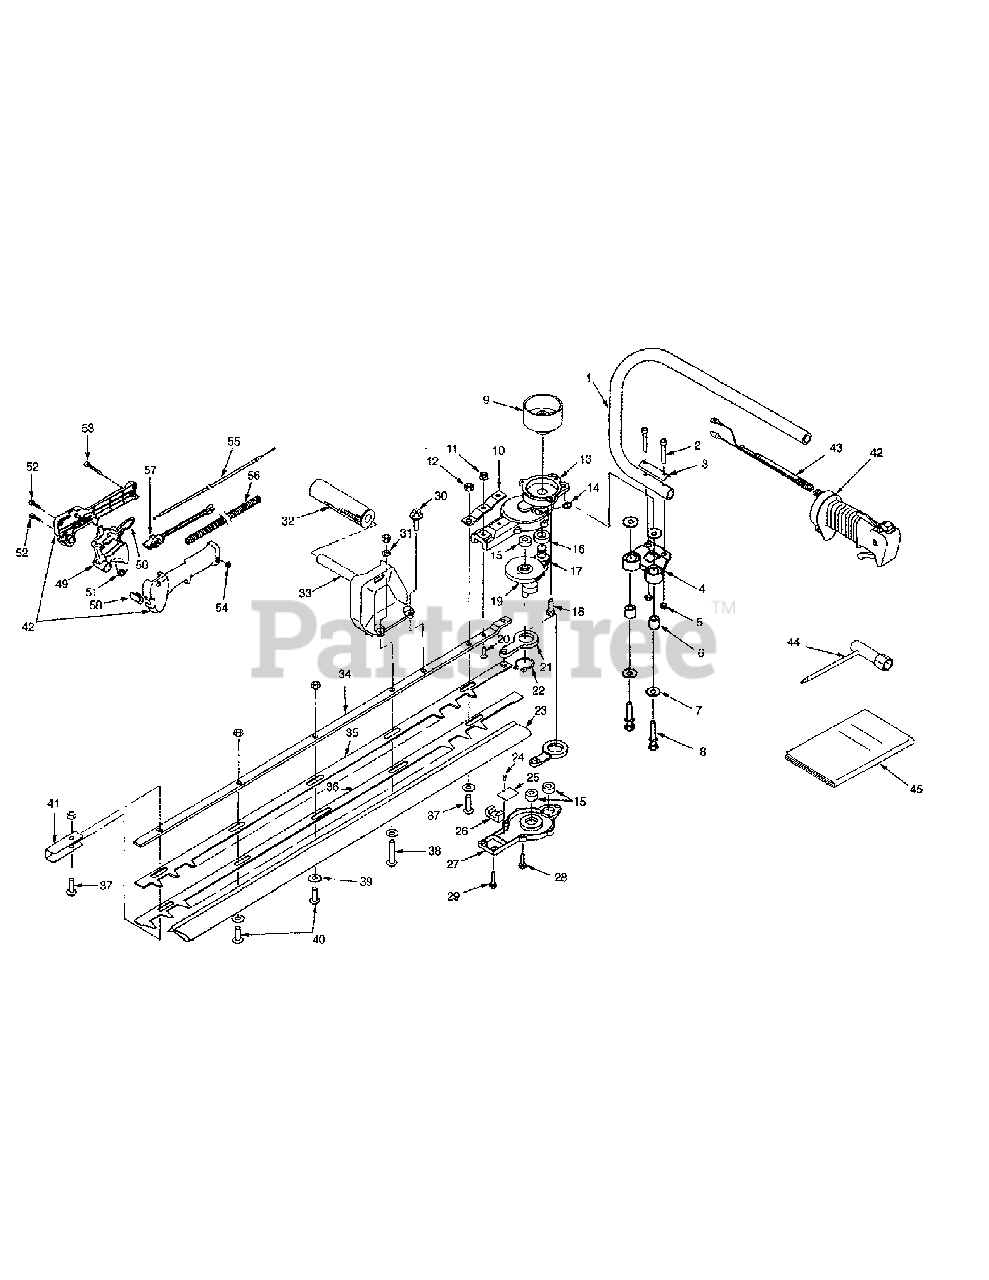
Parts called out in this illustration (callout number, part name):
3	Holder, Handle
4	Holder, Handle
9	Drum, Clutch
14	Nipples, Grease
15	Bearing, Ball, 6082
16	Bearing, Ball, 6001 LL
17	Gear, Pinion
20	Screw, M5x20
22	Snap Ring, S-26
23	Cover, Balde
42	Lever Assembly, Throttle
43	Wire Complete, Throttle
44	Wrench, Spanner Box 19
45	Manual, Operator's
49	Lever
53	Screw, M5x30
55	Wire Compl, Throttle
56	Hose
57	Stop, Switch
